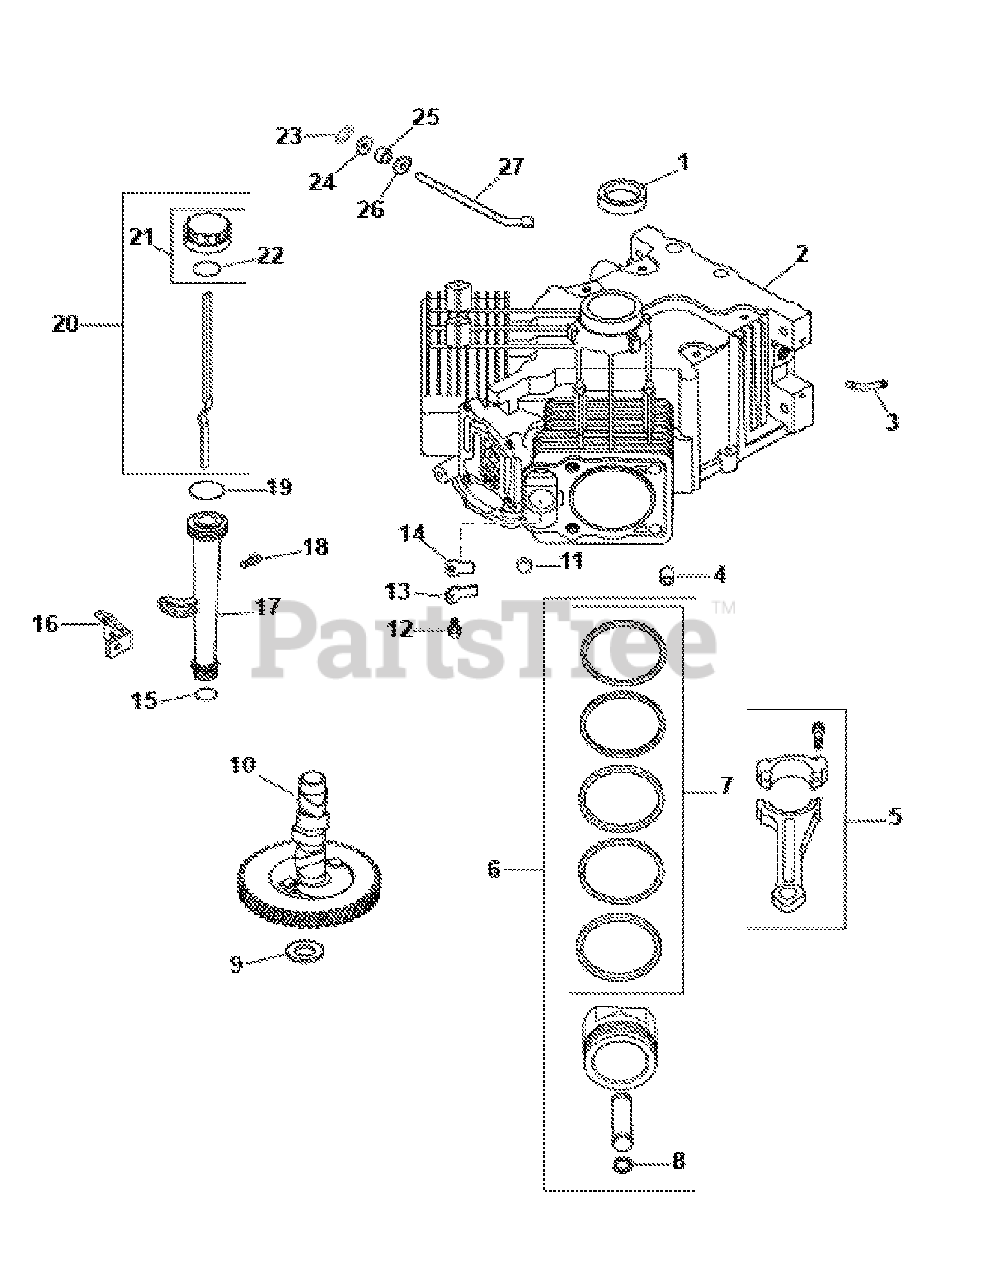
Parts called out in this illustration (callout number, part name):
4	Split Dowel Pin
5	Connecting Rod (Std.)
5	Connecting Rod (.25)
6	Piston w/Ring Set Kit (Std.)
6	Piston w/Ring Set Kit (.08.)
6	Piston w/Ring Set Kit (.25.)
6	Piston w/Ring Set Kit (.50.)
7	Ring Set (Std. & .08)
7	Ring Set (.25)
7	Ring Set (.50)
8	Piston Pin Retainer
9	Shim (White)
9	Shim (Blue)
9	Shim (Red)
9	Shim (Yellow)
9	Shim (Green)
9	Shim (Gray)
9	Shim (Black)
10	Camshaft Kit
13	Reed Retainer
14	Breather Reed
16	Oil Fill Tube Bracket
17	Oil Fill Tube
18	Screw
19	O-Ring Upper Fill Tube
21	Oil Fill Cap Kit
23	Ring Retainer
24	Plain 9mm washer
25	Oil Governor Shaft Seal
27	Governor Cross Shaft
